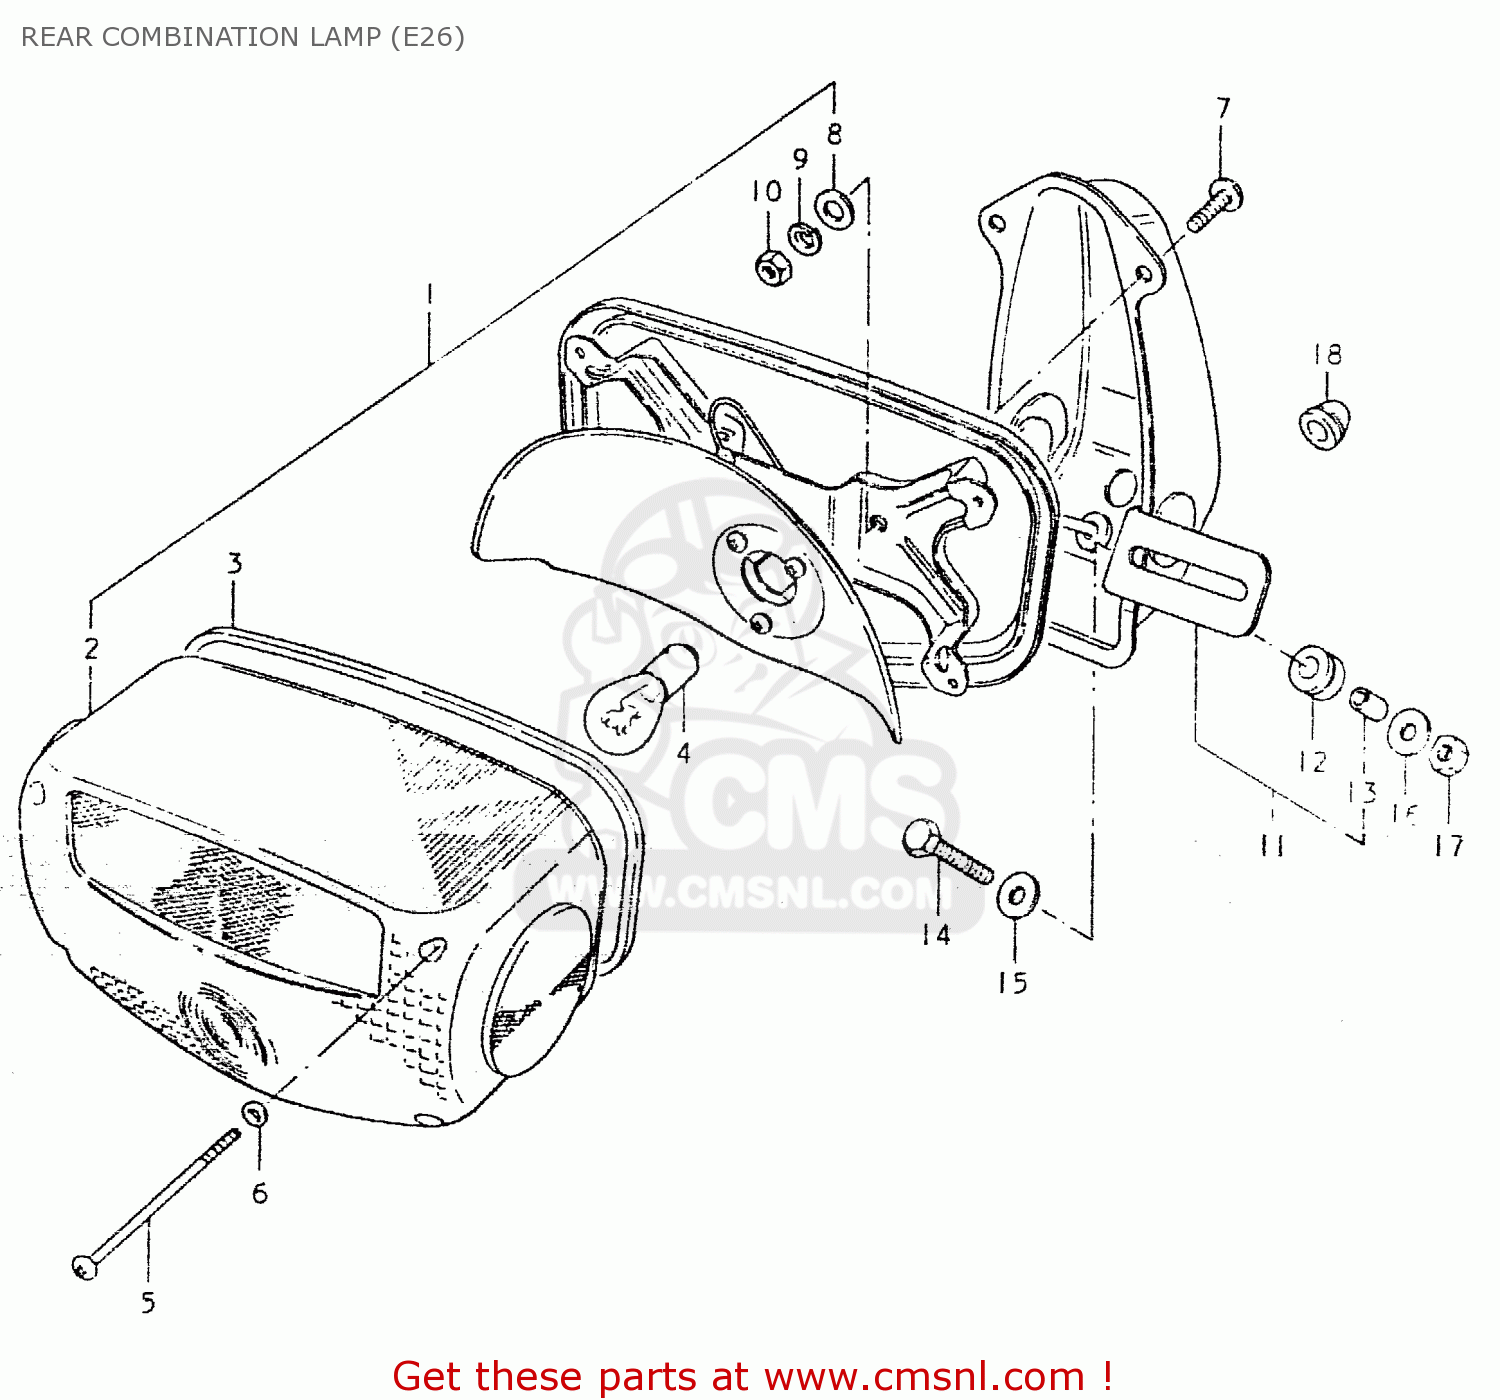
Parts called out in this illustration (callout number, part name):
1	LAMP UNIT, TAIL
2	LENS,REAR COMBINATION LAMP
3	GASKET (NAS)
4	BULB 12V21/5W
5	SCREW (4X55)
6	GASKET (NAS)
7	SCREW 6X12
8	WASHER
9	LOCK WASHER
10	NUT
11	BRACKET ASSY
12	CUSHION
13	SPACER,REAR COMBINATION LAMP
14	BOLT
15	WASHER (6.5X20X1.2)
16	WASHER
17	NUT
18	GROMMET
